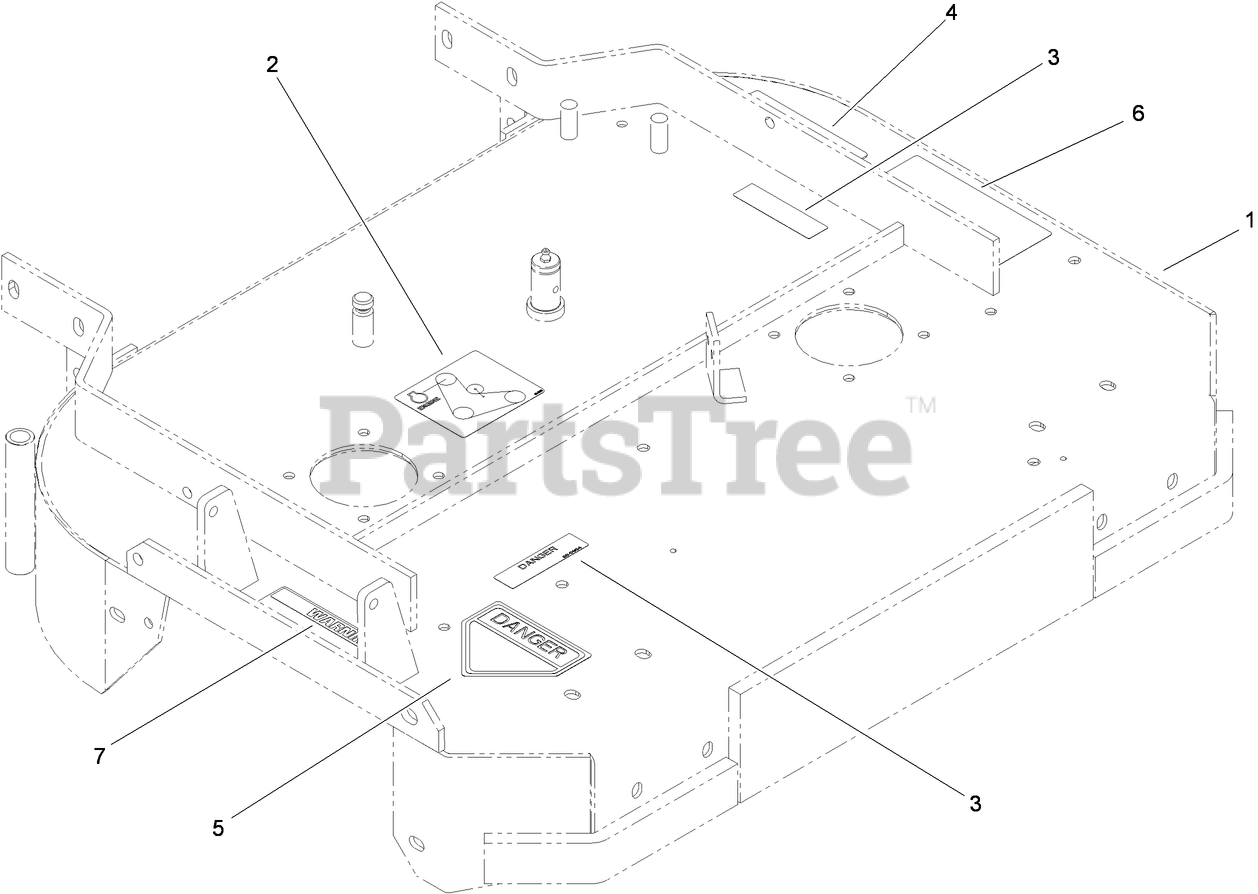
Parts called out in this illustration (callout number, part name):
1	Deck
2	DECAL-ROUTING, BELT
3	DECAL-COVER, MISSING
4	DECAL-TORQUE, BOLT
5	DECAL-DANGER
6	DECAL-DANGER, THROWN OBJECT
7	DECAL-WARNING
